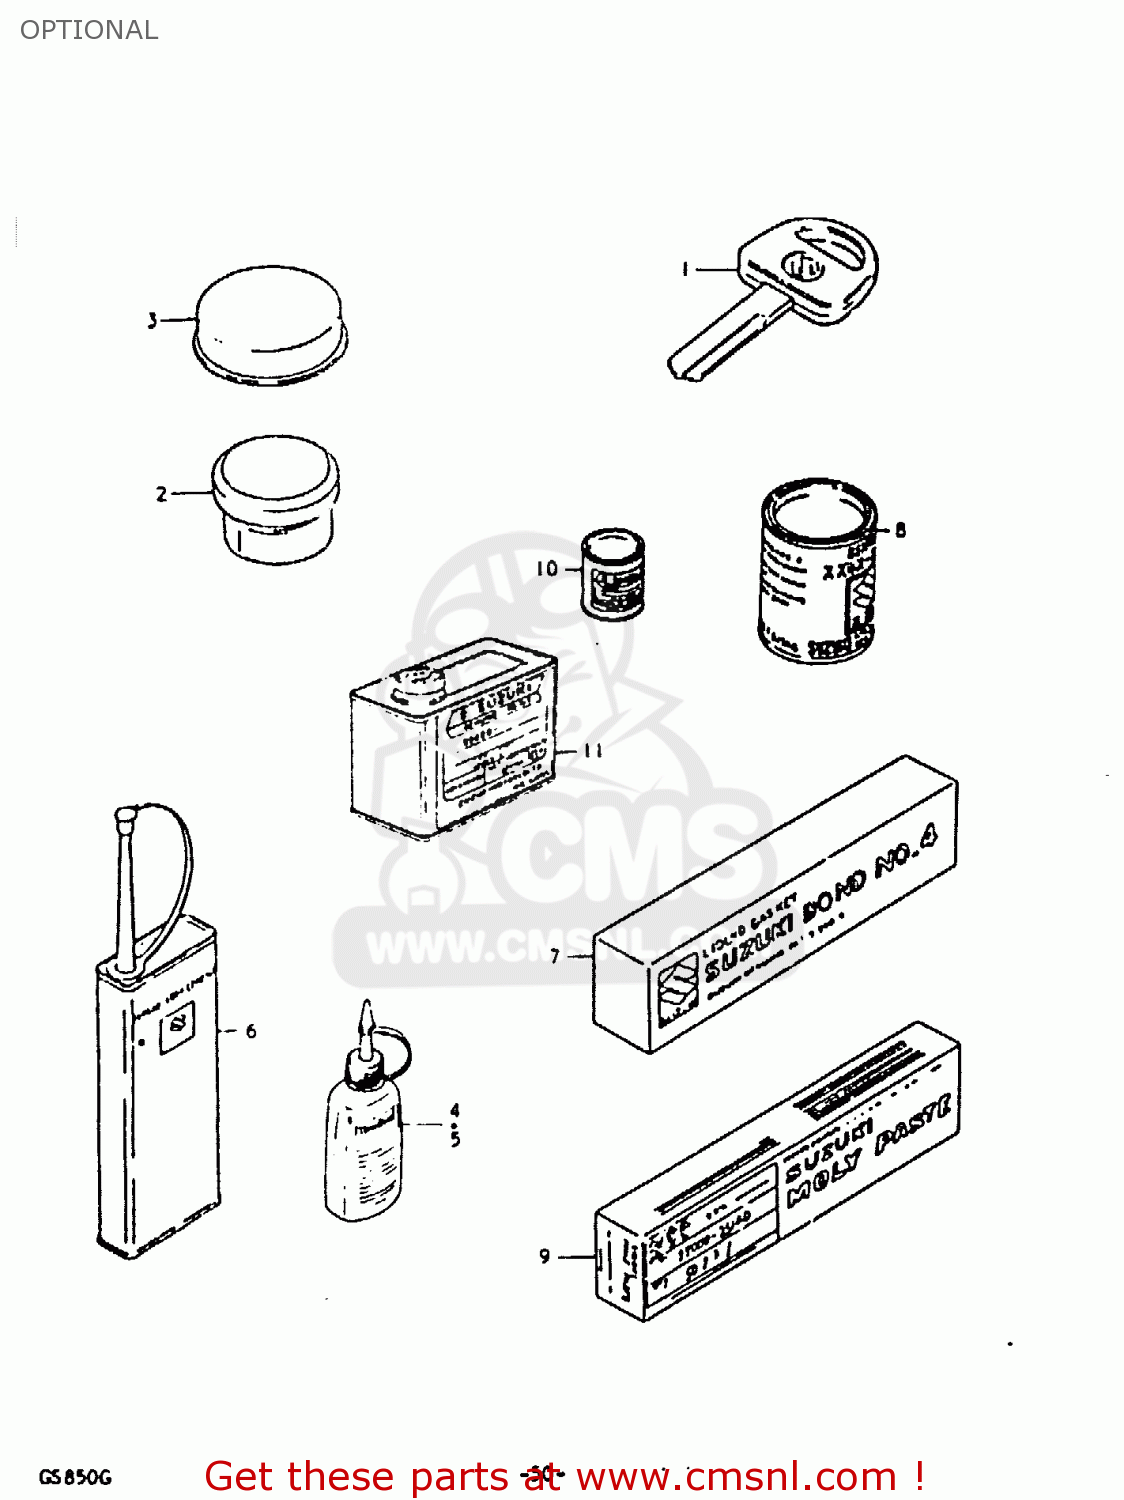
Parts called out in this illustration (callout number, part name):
1	KEY,BLANK
2	GREASE,PBC FOR BRK PAD 20G
3	GREASE,SILICON 20G
4	THREAD LOCK(1333B RED 50G)
5	THREAD LOCK NO.1342
6	THREAD LOCK NO.1401 CLEAR 200G
7	BOND 1104
8	GREASE(C)EP2 LITHIUM 150G
9	SUZUKI MOLY PASTE
10	PAINT,BLACK
11	PAINT (BLACK)
